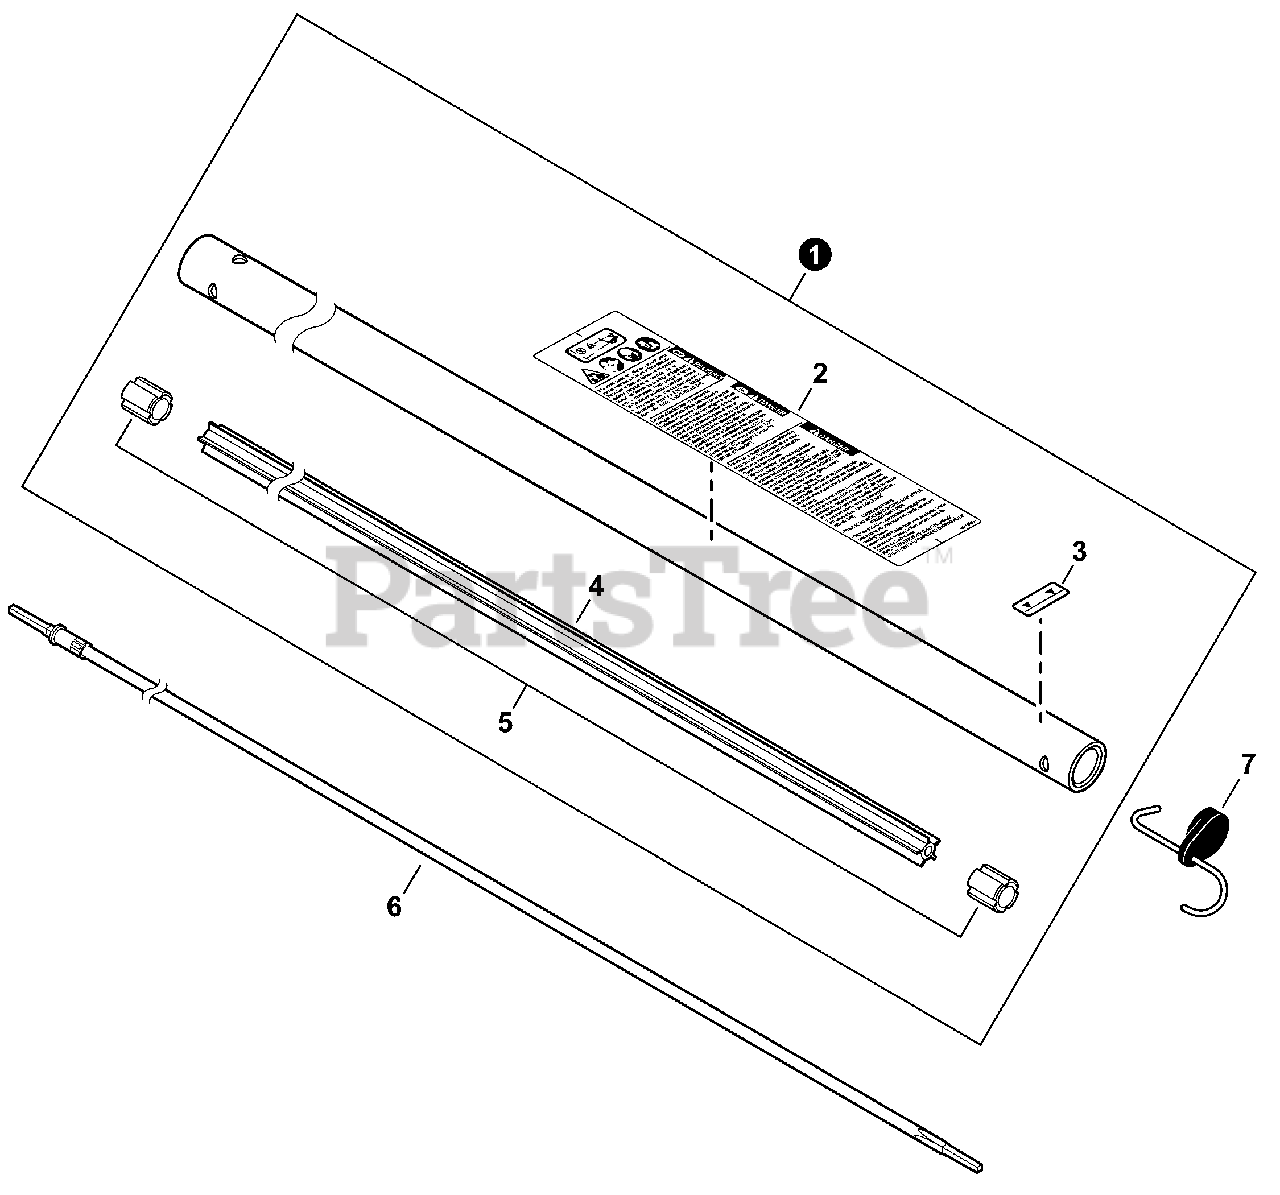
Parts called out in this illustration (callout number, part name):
1	MAIN PIPE ASSY
2	LABEL, CAUTION
3	LABEL - ALIGNMENT
4	LINER - FLEXIBLE
6	DRIVESHAFT - FLEXIBLE
7	HANGER, ATTACHMENT
